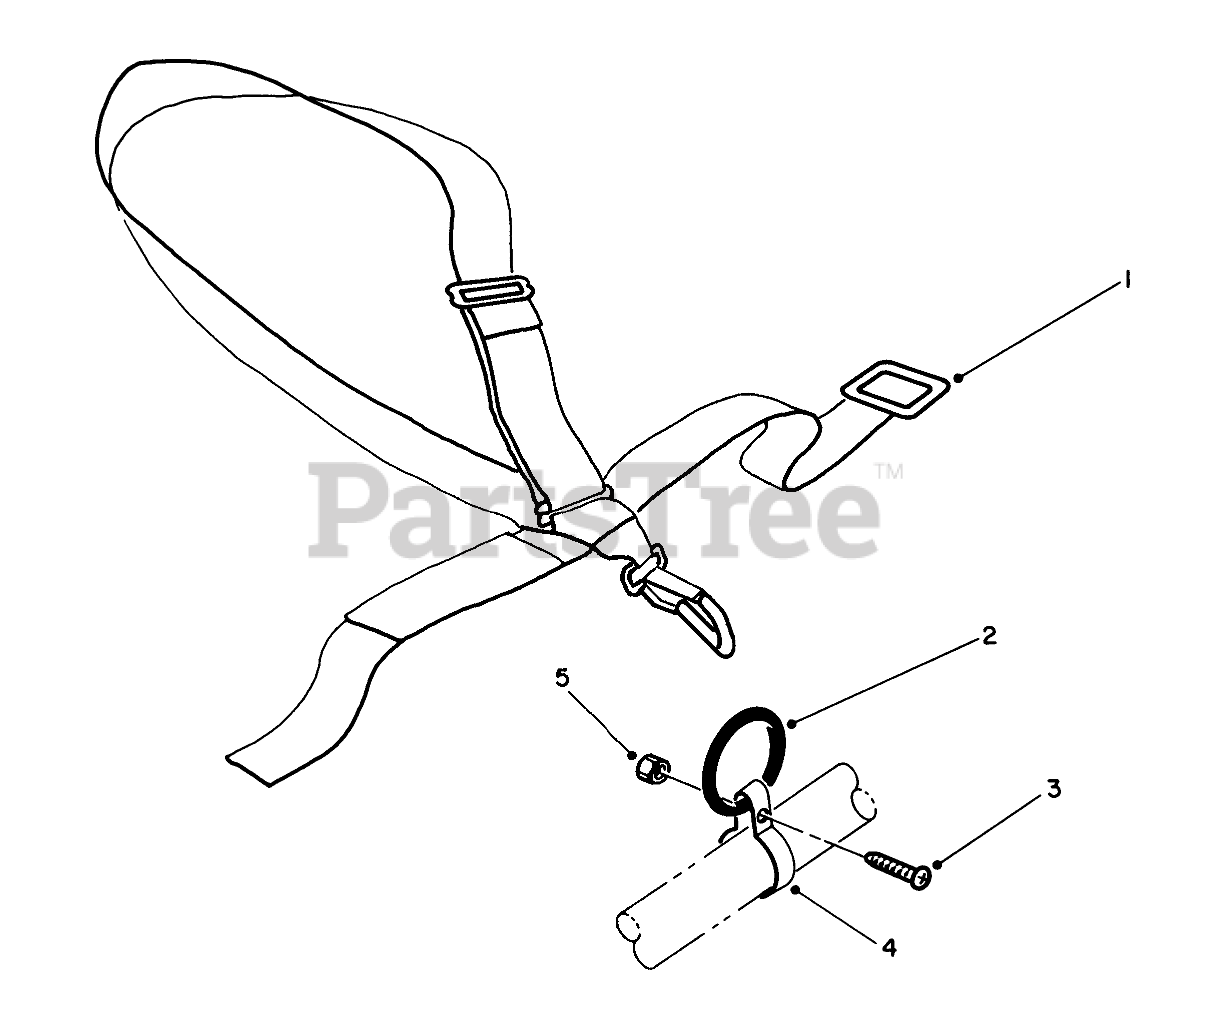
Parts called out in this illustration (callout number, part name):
1	Deluxe Harness
2	Ring
3	SCREW-SRH
4	Clamp
5	NUT-LOCK, NI
